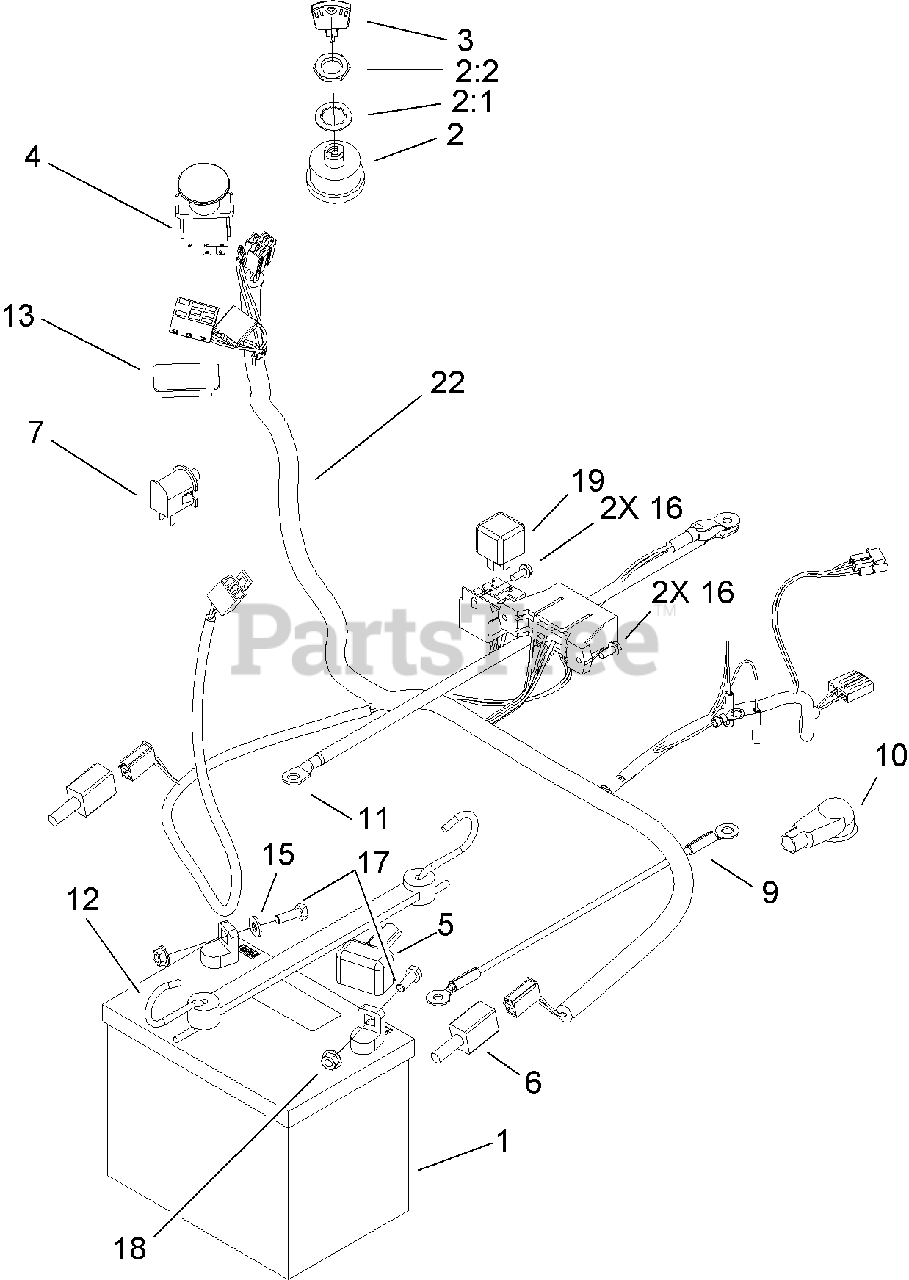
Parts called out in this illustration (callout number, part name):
1	BATTERY-DRY
2	Key Switch ASM
2:1	WASHER-TOOTH
4	SWITCH-PTO
5	BOOT-TERMINAL
7	SWITCH-BAIL
9	WIRE ASM
10	BOOT-INSULATOR, TERMINAL
12	HOLDDOWN-BATTERY
13	PLUG-HOLE
15	WASHER-FLAT
16	SCREW-TAPTITE
17	SCREW-HH
22	HARNESS-WIRE
